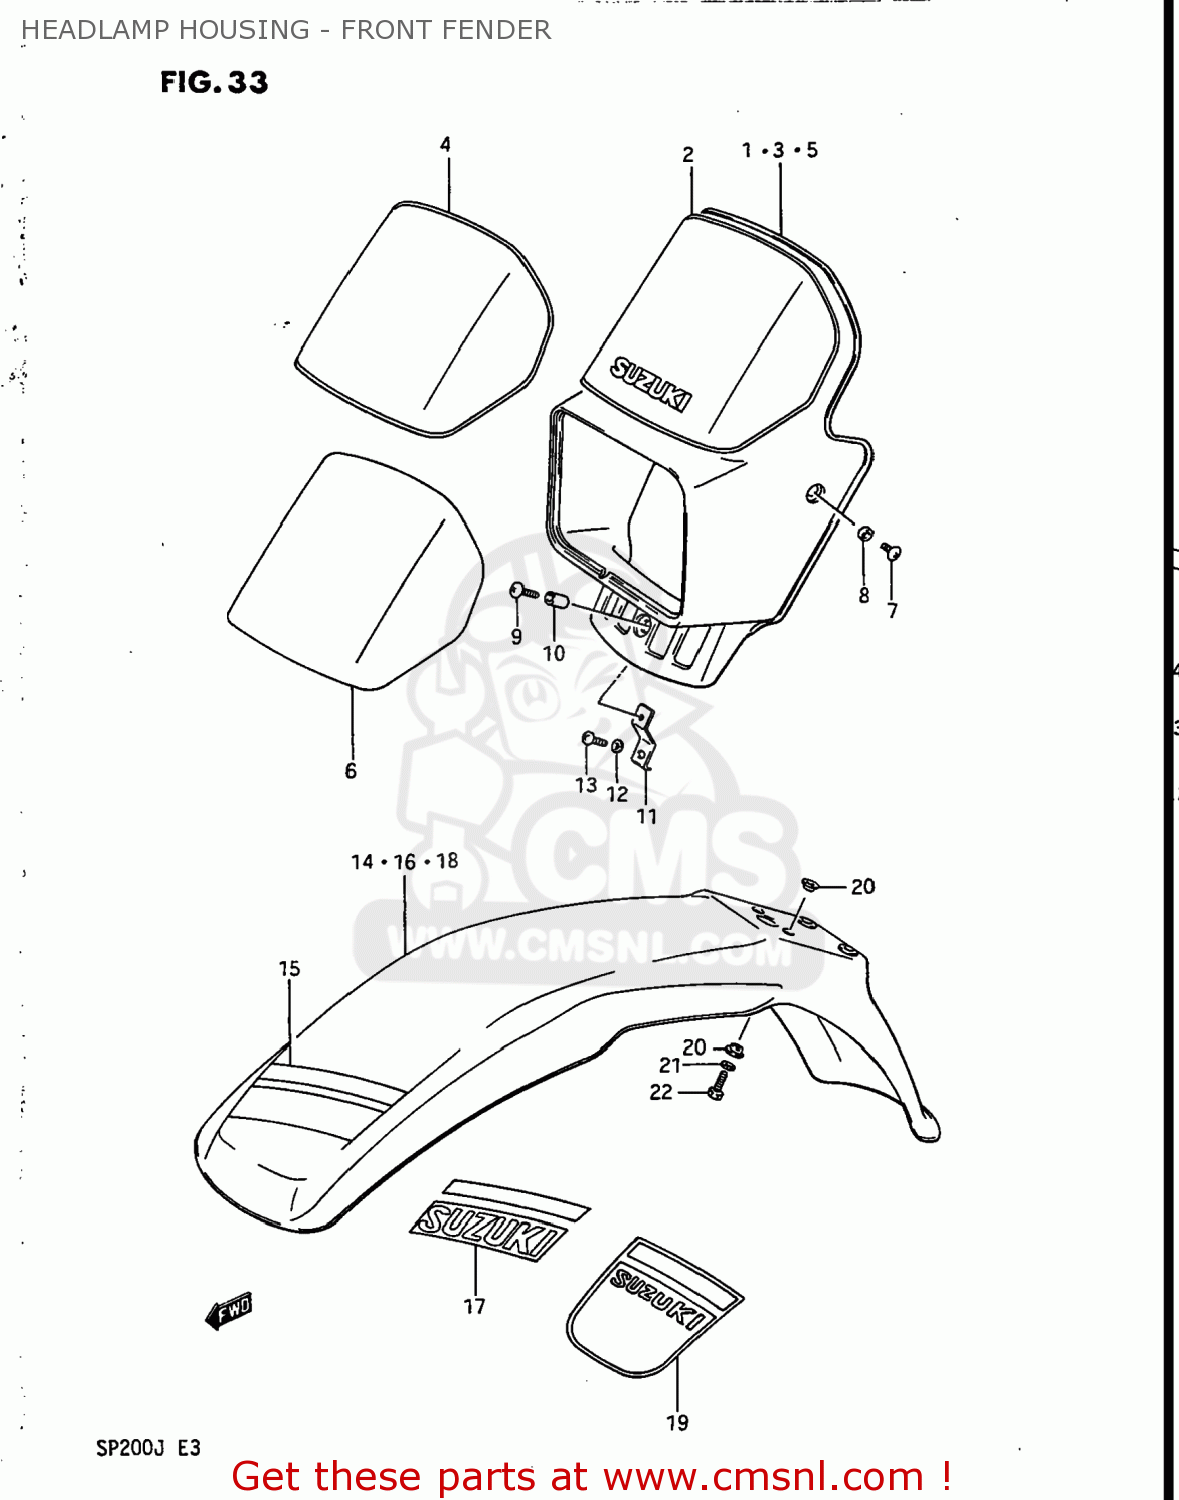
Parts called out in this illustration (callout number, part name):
1	COVER,HEADLAMP
2	TAPE SET,HEADLAMP COVER
3	COVER COMP,HEADLAMP
4	TAPE SET,HEADLAMP COVER
5	COVER,HEADLAMP (RED)
6	TAPE SET,HEADLAMP COVER S
7	SCREW 6X12
8	SPACER (6.1X8X3.5)
9	SCREW, CENTER
10	SPACER (6.1X8X12)
11	BRACE,HEADLAMP HOUSING LWR
12	WASHER,LOCK
13	SCREW 6X12
14	FENDER,FRONT
15	TAPE SET,FRONT FENDER
16	FENDER,FRONT
17	TAPE SET,FRONT FENDER
18	FENDER,FRONT (RED)
19	TAPE,FRONT FENDER
20	WASHER
21	WASHER,LOCK
22	BOLT
